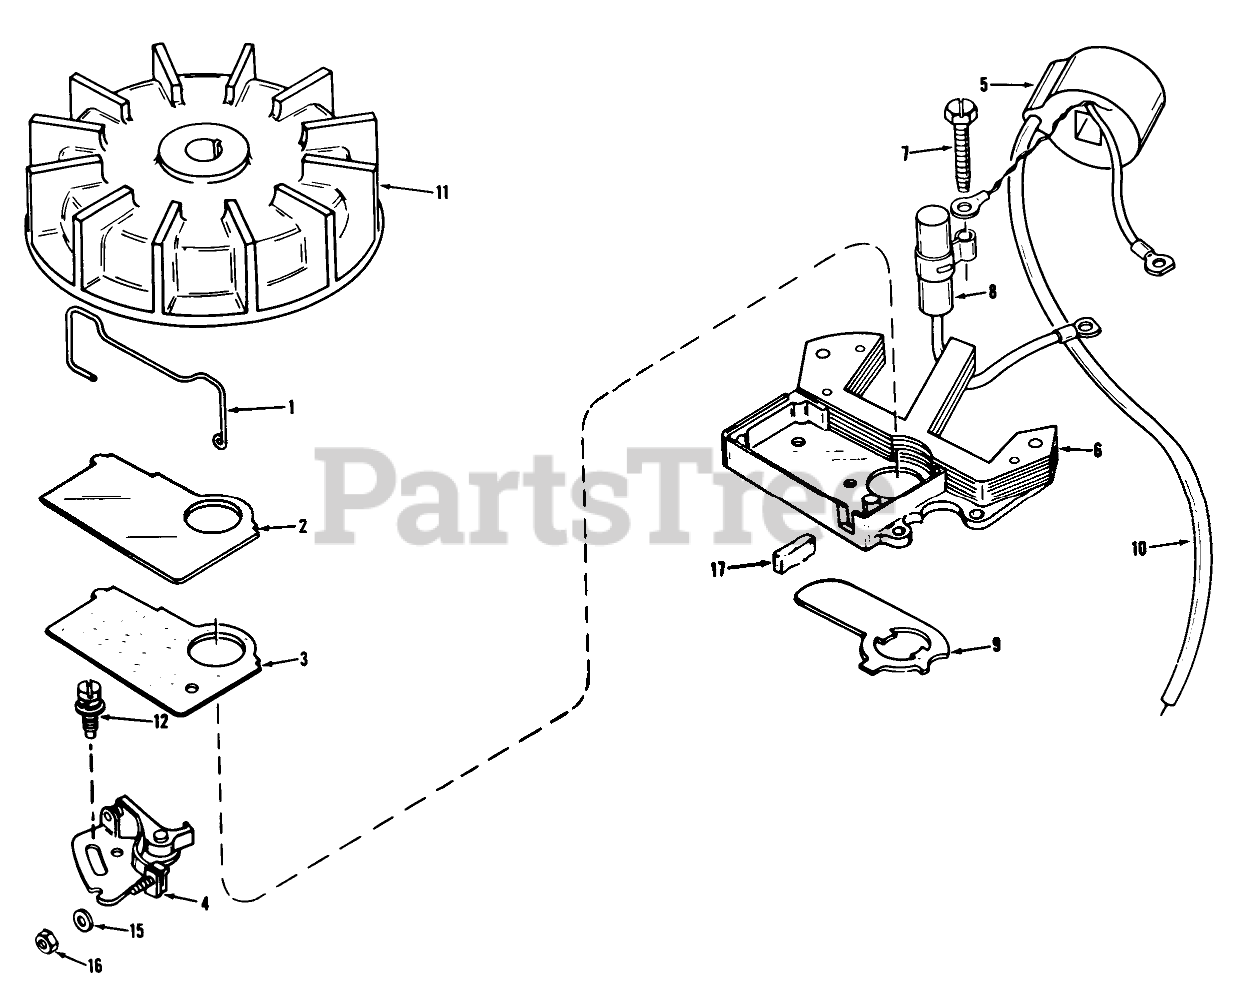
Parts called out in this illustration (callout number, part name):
1	Dust Cover Spring
2	Dust Cover
3	Magneto
4	Hose-Primer 209543
5	Coil Assy.
6	Gasket 209542
7	Condenser Screw
8	Condenser Assy.
9	Sealing Washer
10	Wire, Lead
11	RETAINER WASHER(SET OF 10)
12	Breaker Screw
17	Cam Felt
